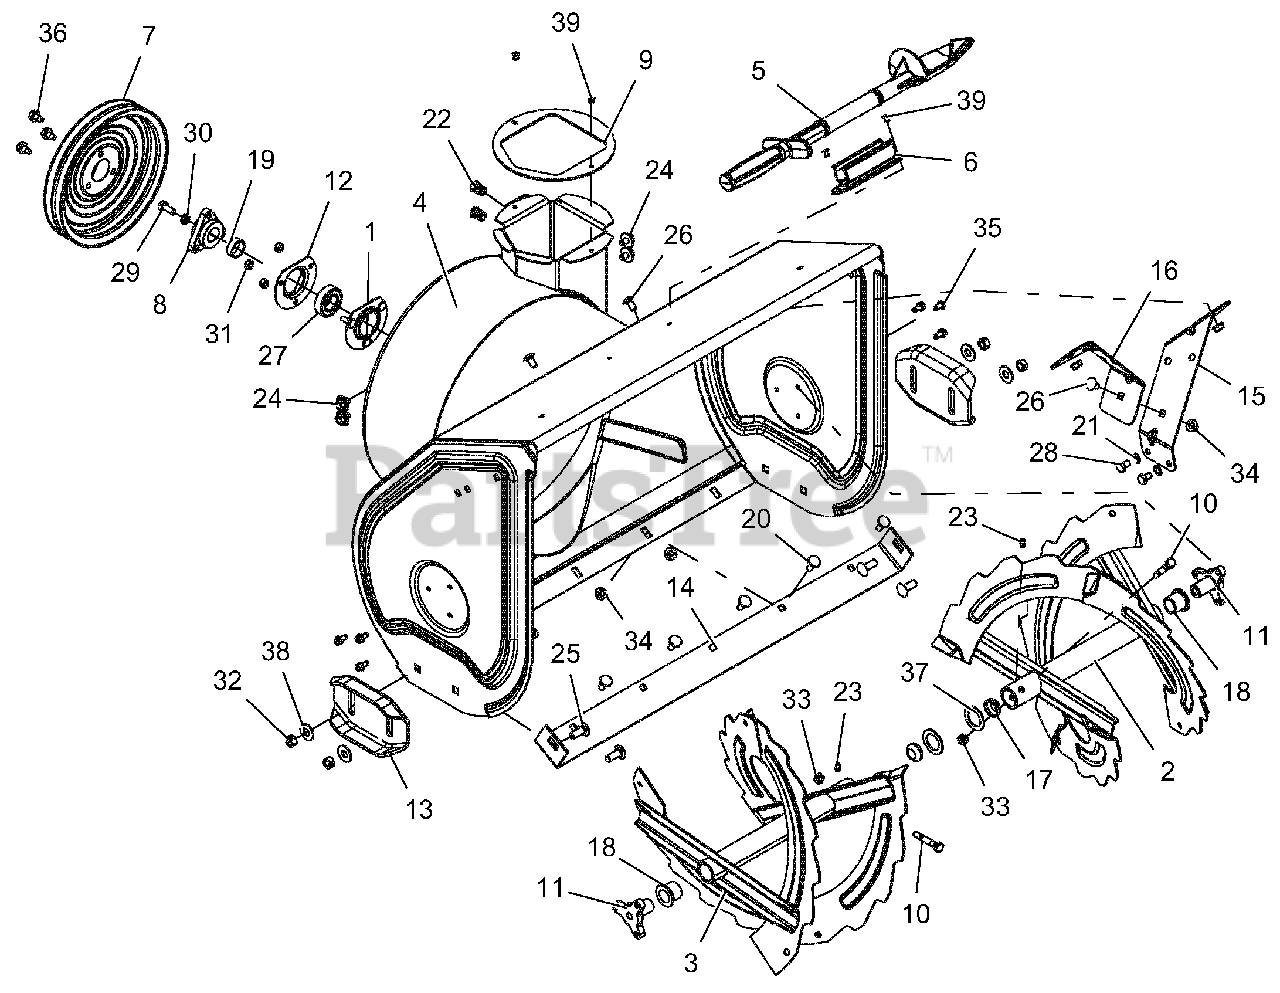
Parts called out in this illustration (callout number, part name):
1	BEARING FLANGE
2	RAKE, LEFT HAND-28" DELUXE
3	RAKE, RIGHT HAND-28" DELUXE
4	HOUSING, BLOWER - 28" DELUXE
5	DEVICE, SNOW CLEAN OUT
6	MOUNT, SNOW CLEAN OUT
7	PULLEY, SPIN FORM DUAL GROOVE
8	PULLEY HUB, D-BORE .87 DELUXE
9	BAFFLE, DISCHARGE NECK
10	SHEAR BOLT SERVICE ASSEMBLY
11	SHEAR BOLT SERVICE ASSEMBLY
12	BEARING FLANGE
13	SKID SHOE, REVERSIBLE - ORANGE
14	BLADE, SCRAPER - 28"
15	BRACKET, GEARCASE SUPPORT - LH
16	BRACKET, GEARCASE SUPPORT - RH
17	PLUG, RAKE TUBE
18	BSHG-FLG, NY.778 ID X 1.018 OD
19	BSHG-SPCR .895IDX1.065ODX.353
20	BOLT, MODIFIED HEAD CARRIAGE
21	@WSHR-LK-EXT.326X.599X.031YWZC
22	NUT, THREADED INSERT .38-16
23	ZERK,FITTING .25X.125 DRIVE IN
24	SCR-TAP.31-18X.50 HWH TR YWZ
25	@BLT-RDHDSHSQNK.38-16X1.0 G5YZ
26	BLT-RDHDSQSHNK.31-18X.62 YZ-LK
27	BRG-BALL .876X1.75X.50 RSTFP
28	@BLT-HEX .31-18X.50 GR5 YWZC
29	BLT-HEX .31-24X.75 YWZC GR5
30	WSHR-LK .312X.097 HVY YWZC
31	@NUT-LK-CTR .25-20 YWZC
32	@NUT-LK-CTR .38-16 YWZC
33	NUT-LK-CTR .31-18 YWZC
34	@NUT-LK-TOP-FLG .31-18 YWZC
35	SCR-TAP .25-20X.50 HWH TR YWZ
36	@SCR-TAP .31-18X.50 HWH TR YWZ
37	WSHR-FL-STL 1.010X1.505X.062YZ
38	@WSHR-FL-STL.438X1.00X.083 YWZ
39	RVT-POP .187 YZ
